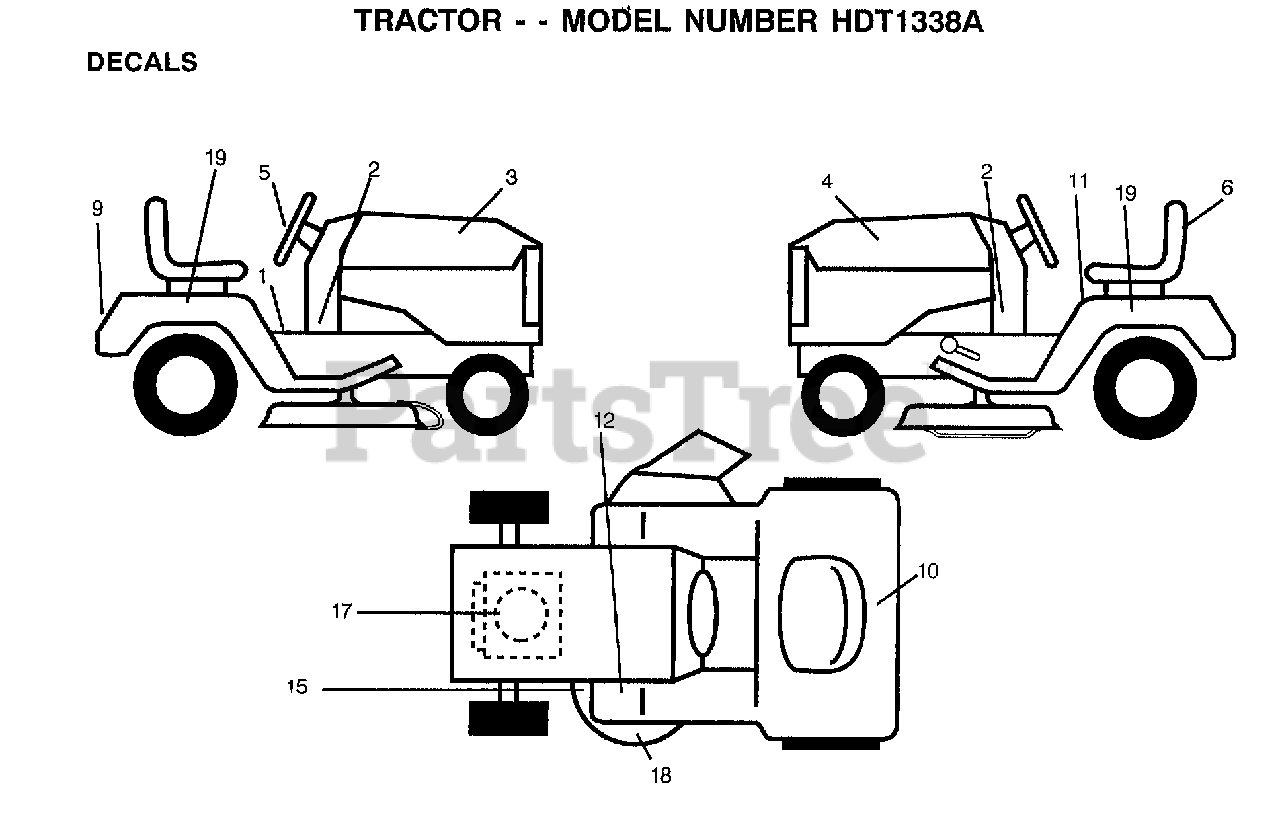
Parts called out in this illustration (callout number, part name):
3	DECAL.HOOD.RH
4	DECAL.HOOD.LH
5	DECAL, INS STRG WH
9	DECAL.FENDER.LOGO
10	DECAL.BATRY.3-3908
11	"DECAL FENDER,DANG"
12	DECAL CLUT/BRAKE
15	DECAL
18	DECAL.MOWER.HOME
19	DECAL.FEND.SD.5SP
